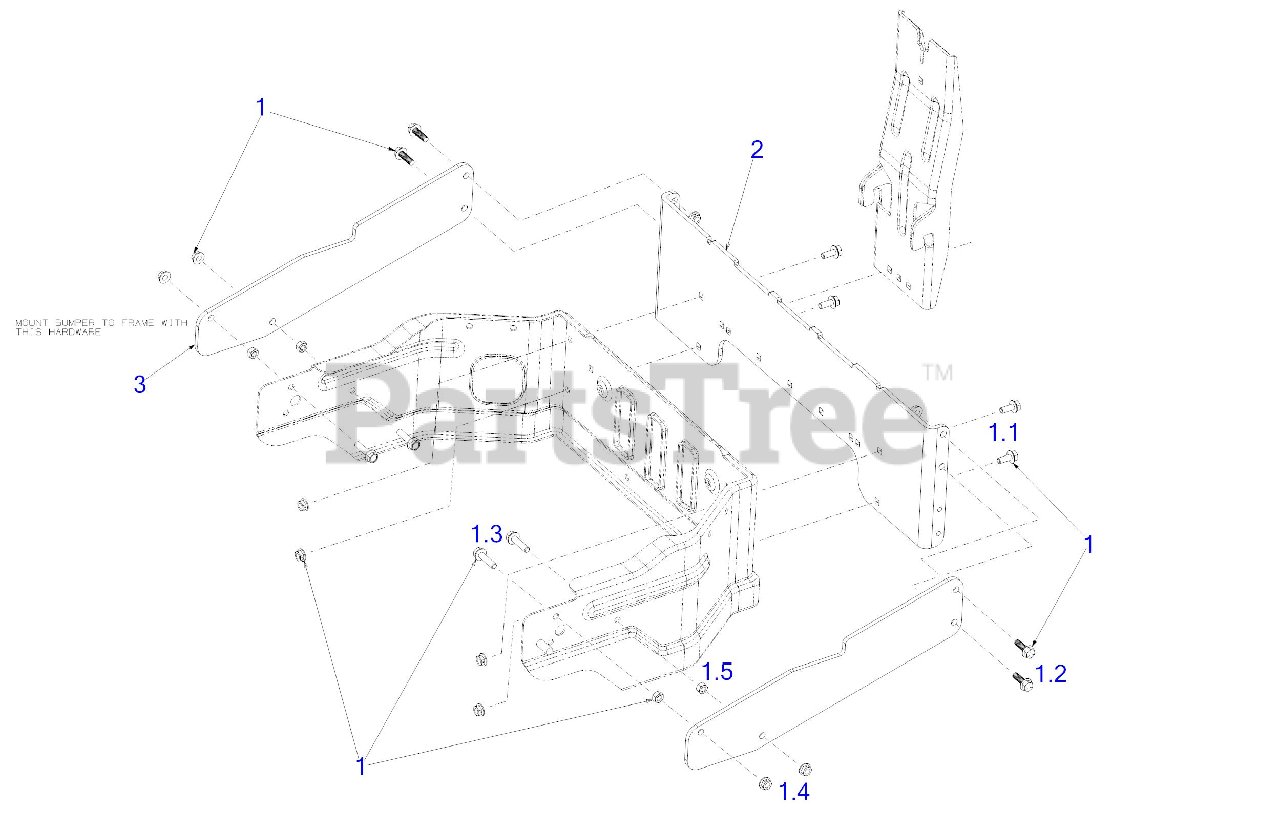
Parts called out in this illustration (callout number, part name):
1	HARDWARE PACK
1.1	SCREW 5/16-18
1.2	SCREW 5/16-18 x 1 GR5
1.3	SCREW 5/16-18 x 1.25 GR5
1.4	HEX FLANGE NUT
1.5	HEX NUT
